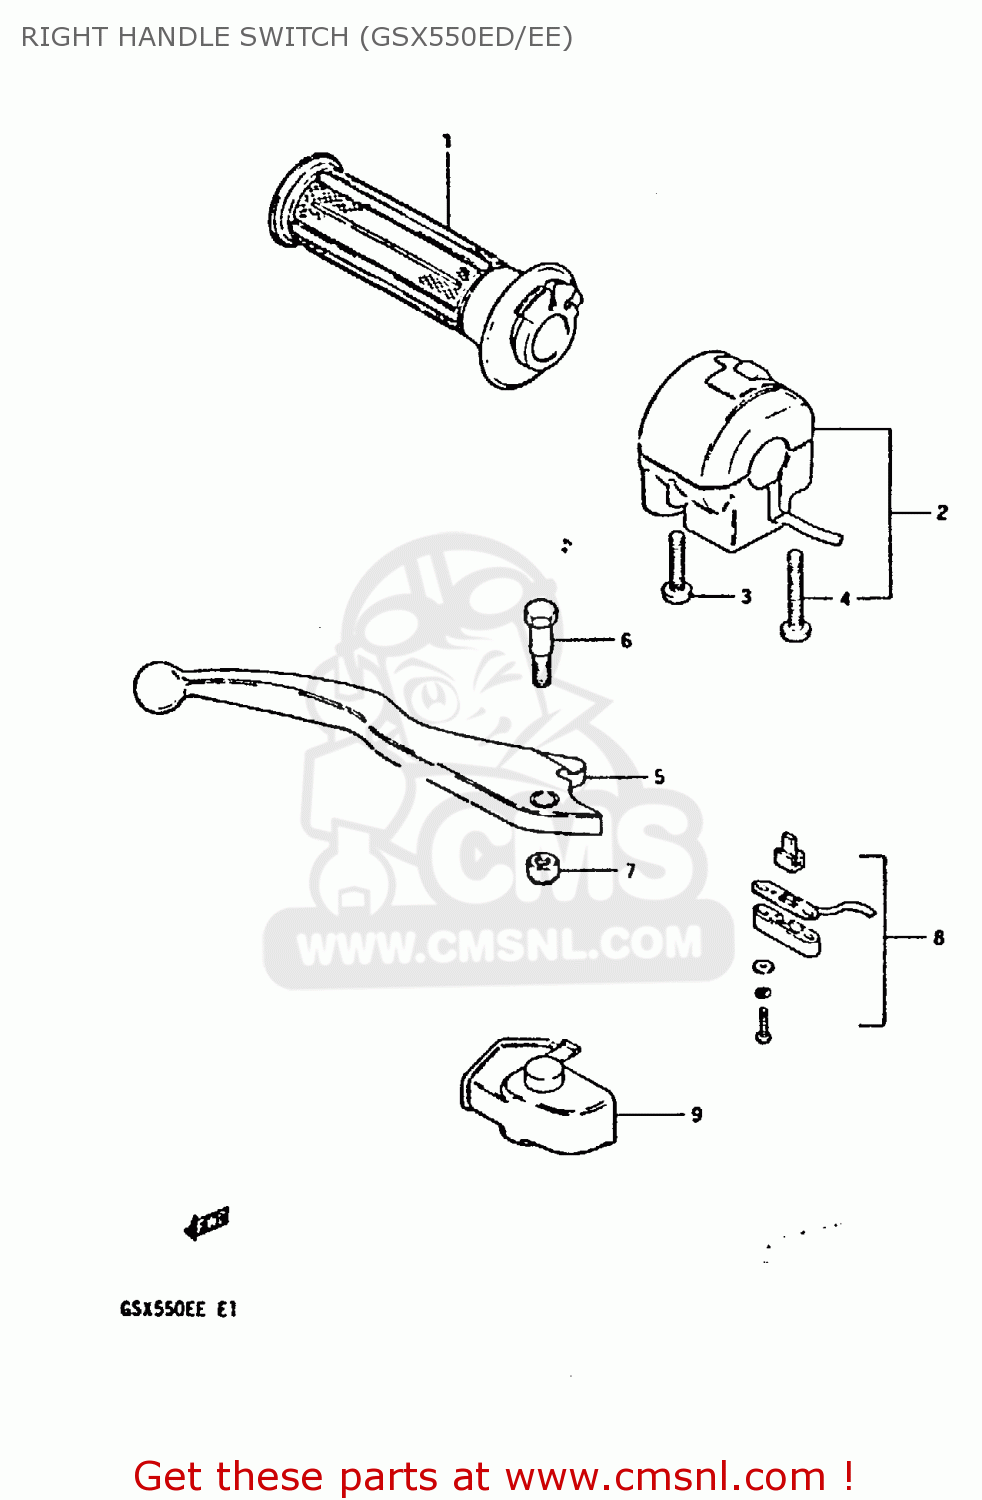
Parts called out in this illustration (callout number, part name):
1	GRIP,THROTTLE
2	SWITCH ASSEMBLY,HANDLE,RIGHT
3	SCREW
4	SCREW
5	LEVER,BRAKE
6	BOLT,LEVER PIVOT
7	NUT 6MM
8	SWITCH ASSEMBLY
9	COVER,BRAKE LEVER
